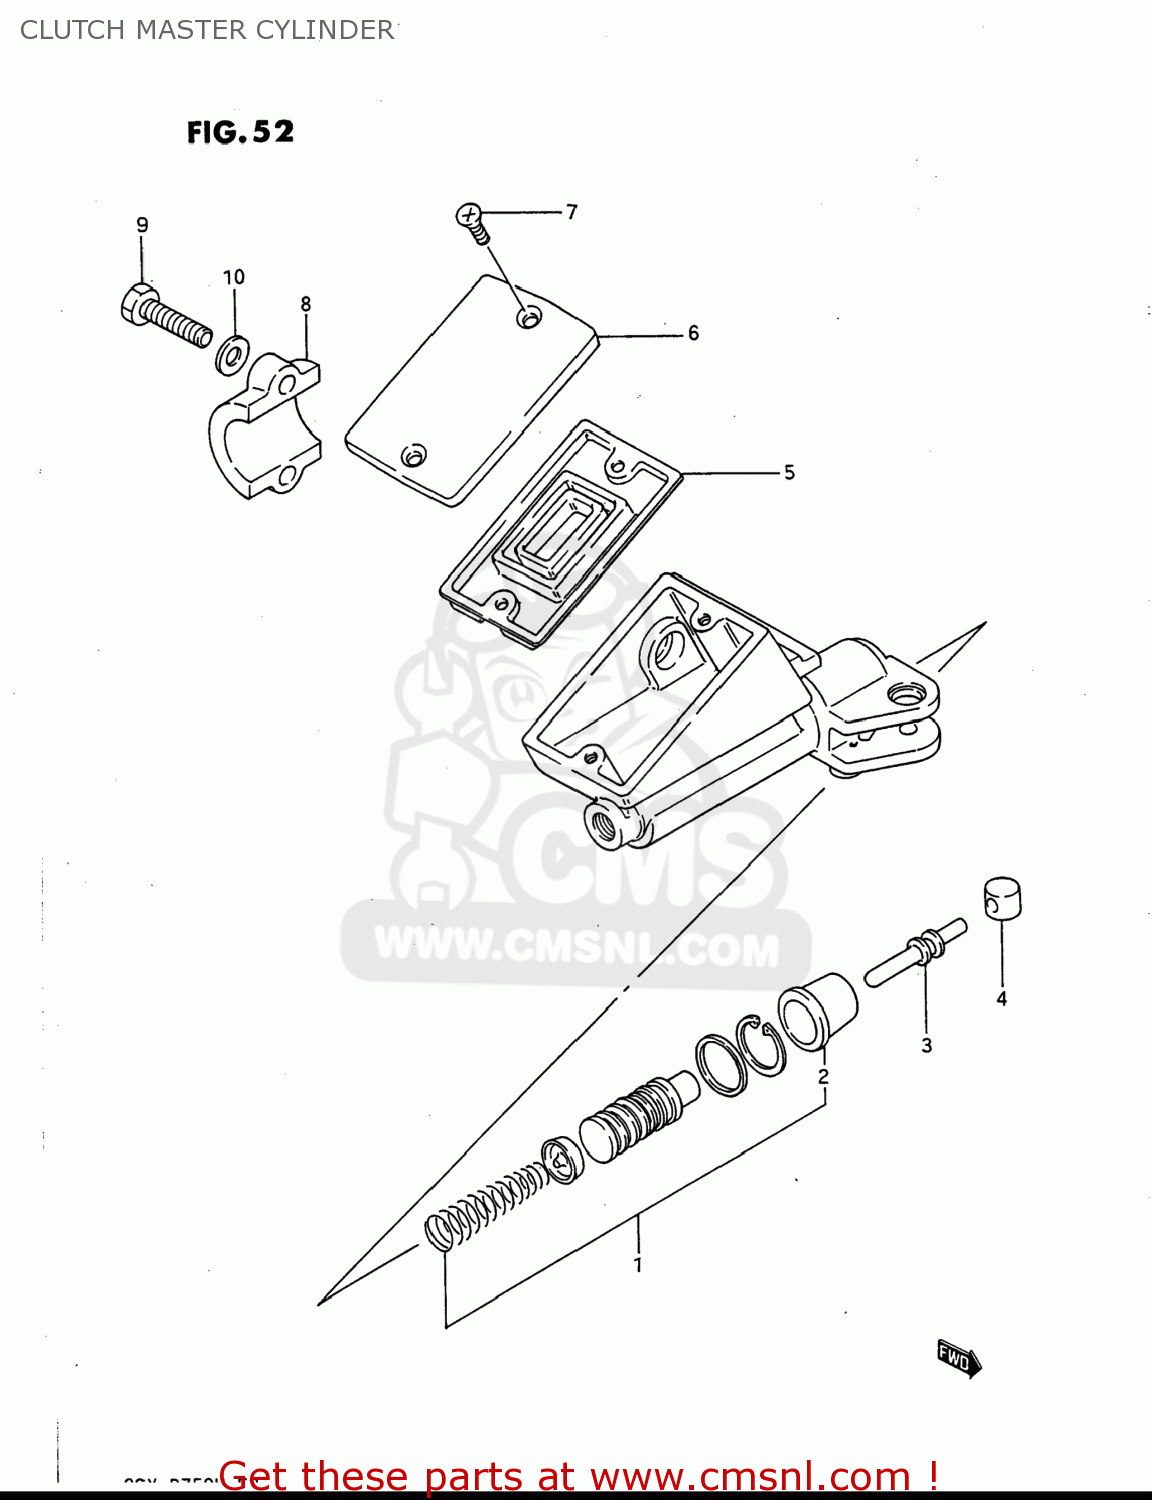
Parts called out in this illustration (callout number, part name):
1	PISTON & CUP SET
2	BOOT
3	ROD,PUSH
4	BUSH
5	6
6	CAP
7	SCREW
8	HOLDER,MASTER CYLINDER
9	BOLT
10	WASHER
